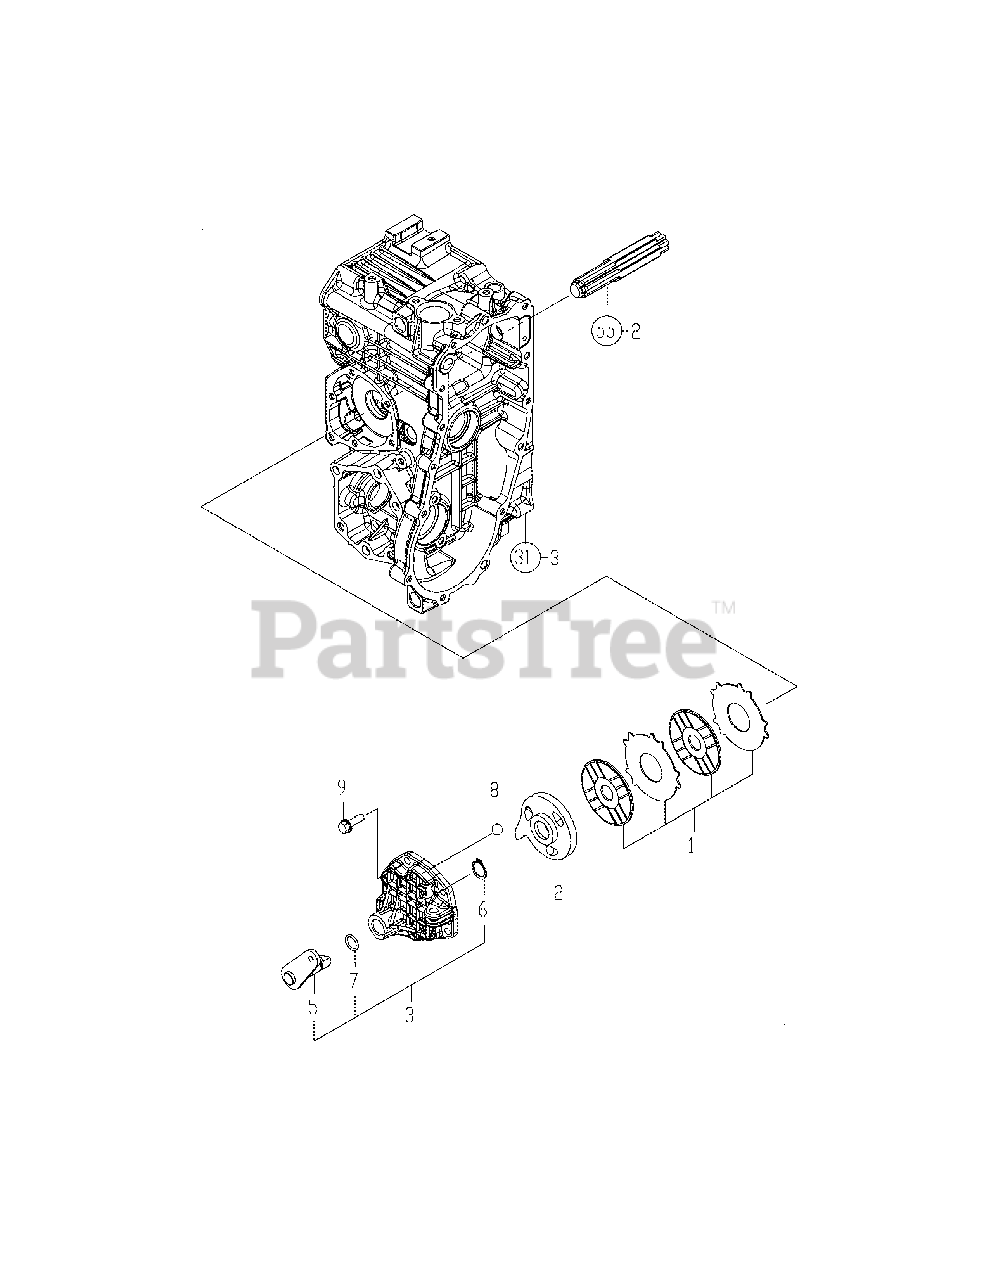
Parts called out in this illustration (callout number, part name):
1	Plate Kit, Brake
3	Cam Kit, Brake
3-1	Cam Kit, Brake
5	Shaft Assy, Lever
7	Packing, P 16.0
